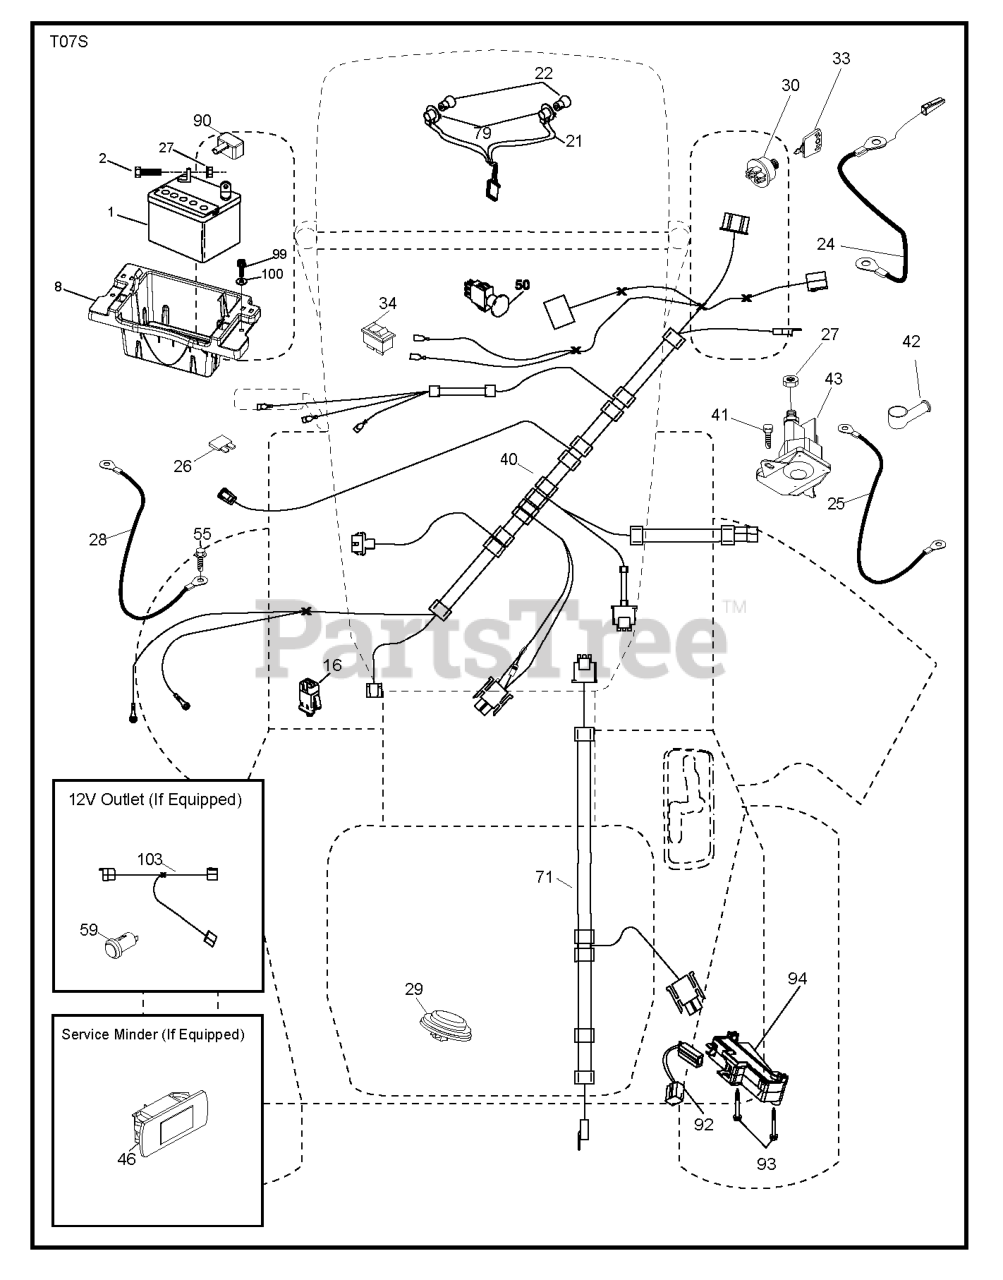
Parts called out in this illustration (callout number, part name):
1	Battery, Dry 30 Amp
2	BOLT.HEX.1/4.X.3/4.DICHROMATE
8	BOX.BATTERY.MOUNT.FRONT.LT
16	SWITCH INTERLOOK PUSH-IN
21	HARNESS.LIGHT W/4152J BULBS
24	CABLE.FRBATT.W/WIRE.8GA.8
25	CABLE.STARTER.8GA.17.5
26	FUSE 20AMP
27	NUT
28	CABLE.GROUND.21"BLK.8GA.90T
29	SWITCH.SEAT.DELTA.OPC.
30	SWITCH.IGN.DELTA.W.LGH.ROS
33	KEY.CHAIN.BLISTER.PACK.GEN.USA
40	HARNESS.IGN.DASH.HUQ/P
41	SCREW
42	TERMINAL COVER
43	SOLENOID.W/BRASS.PLUNGER
46	RP.GUAGE.SRVCMNDR.HRMTR.
50	RP.PTO.SWITCH.8 TERMINAL.BLACK
55	SCREW 5/16"
71	HARNESS-CHASSIS SUB
79	BULB HOLDER ASM.
90	COVER.TERMINAL.BATTERY
91	STRAP.BATTERY.MOUNT.FRONT(2 2)
92	HARNESS.PIGTAIL.CONSLE
93	SCREW.PLASTITE
94	MODULE.REVERSE.ROS
99	SCREW HEXWSHR 1/4-20X3/4
100	WASHER
